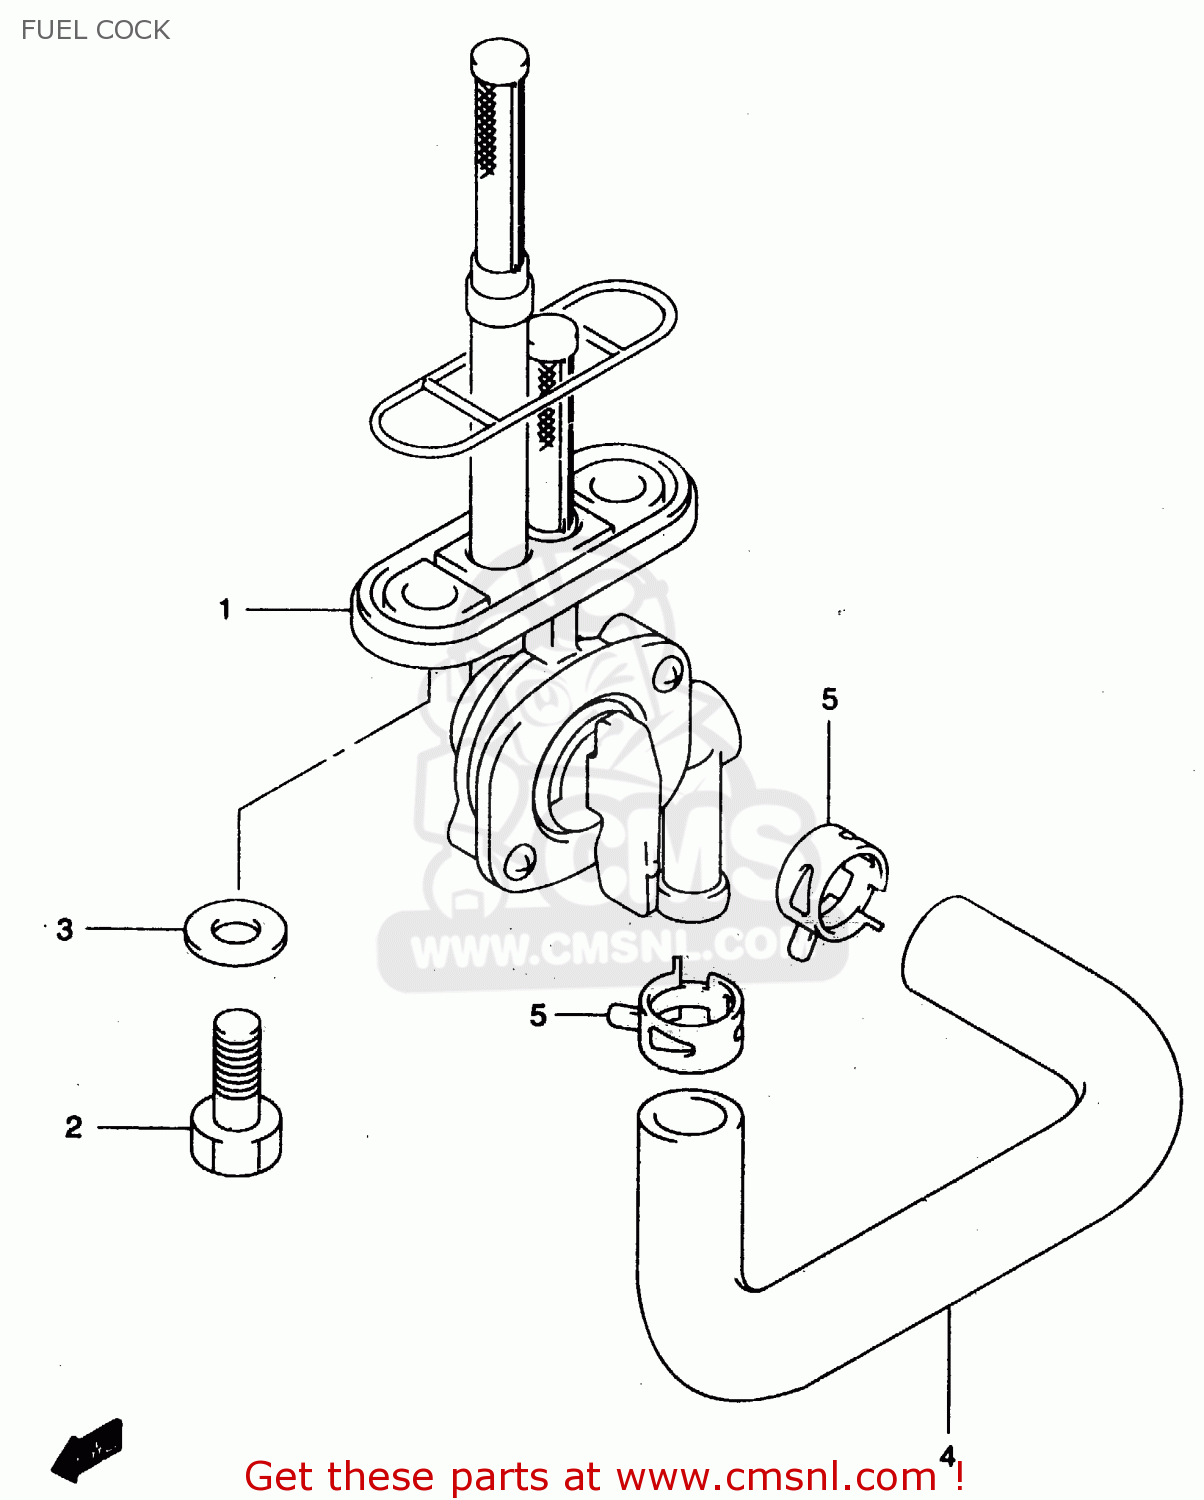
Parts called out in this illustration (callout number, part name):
1	COCK ASSY,FUEL
2	BOLT(6X20)
3	GASKET(6.4X11.5X0.8) (NAS)
4	HOSE(7X12X600)
5	CLIP
